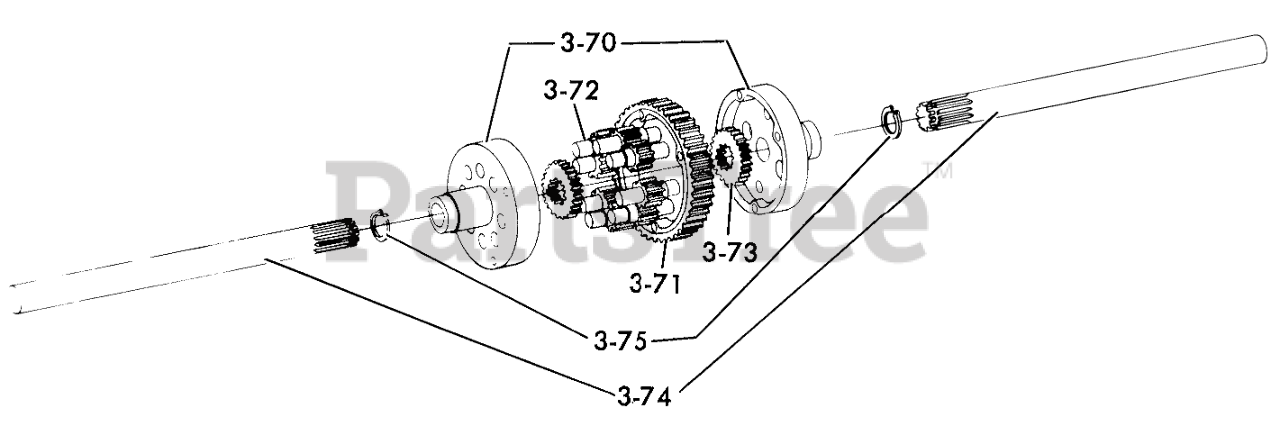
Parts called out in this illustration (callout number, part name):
3-70	DIFFERENTIAL END CAP
3-70	Bolt, 3/8-16
3-70	NUT
3-71	GEAR-DIFFERENTIAL RING, 43T
3-72	GEAR-PINION, 11T
3-73	GEAR-AXLE DIFFERENTIAL
3-74	AXLE-REAR
3-75	RING-SNAP
